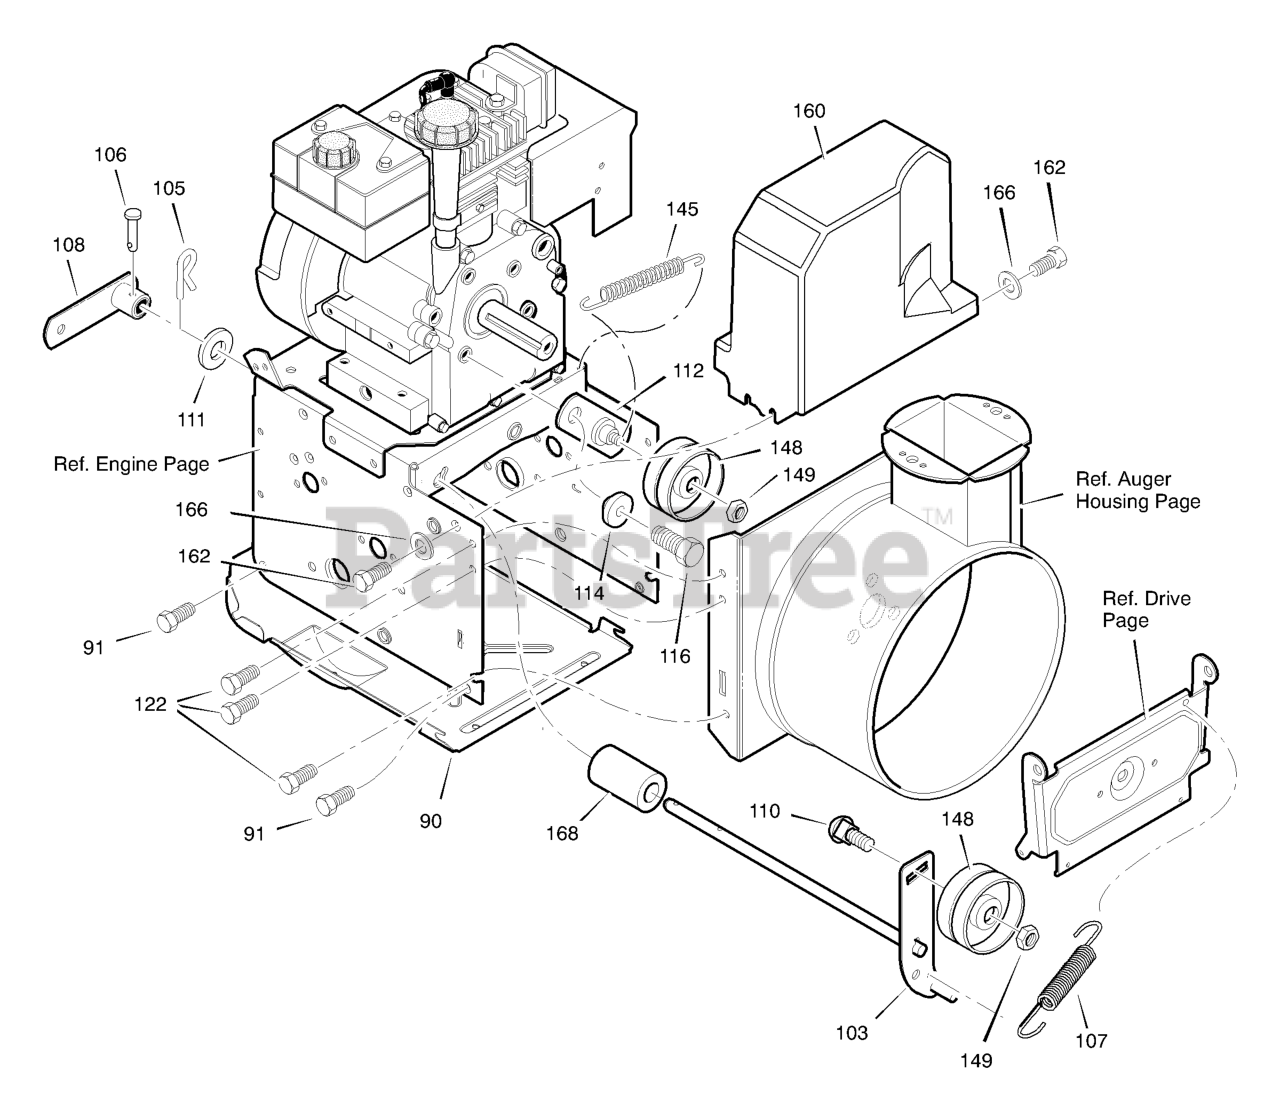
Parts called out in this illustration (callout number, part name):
88	SCREW, 5/16-18 x 0.50
90	COVER, BOTTOM
91	SCREW, 1/4-20X .63
103	IDLER ASSEMBLY, AUGER
105	PIN, HAIR .38DIAX1.64LG
106	PIN, CLEVIS 3/16" DIA
107	SPRING, TENSION
108	ASSY., SPRING ATTACH
110	BOLT, 3/8-16X1.25 CARR.
111	WASHER, FLAT
112	BRACKET ASSEMBLY, IDLER
114	BUSHING, IDLER BRACKET
116	SCREW 5/16-24 X 1.00
118	WASHER, SPLIT
122	SCREW, TAP 5/16-18 X .50
145	SPRING, IDLER TRACTION DRIVE
148	PULLEY, IDLER
149	NUT, JAM 3/8-16
160	COVER, BELT
162	SCREW, TAP 1/4-20 X .63
166	WASHER, FLAT
168	SPACER, AUGER BRACKET
